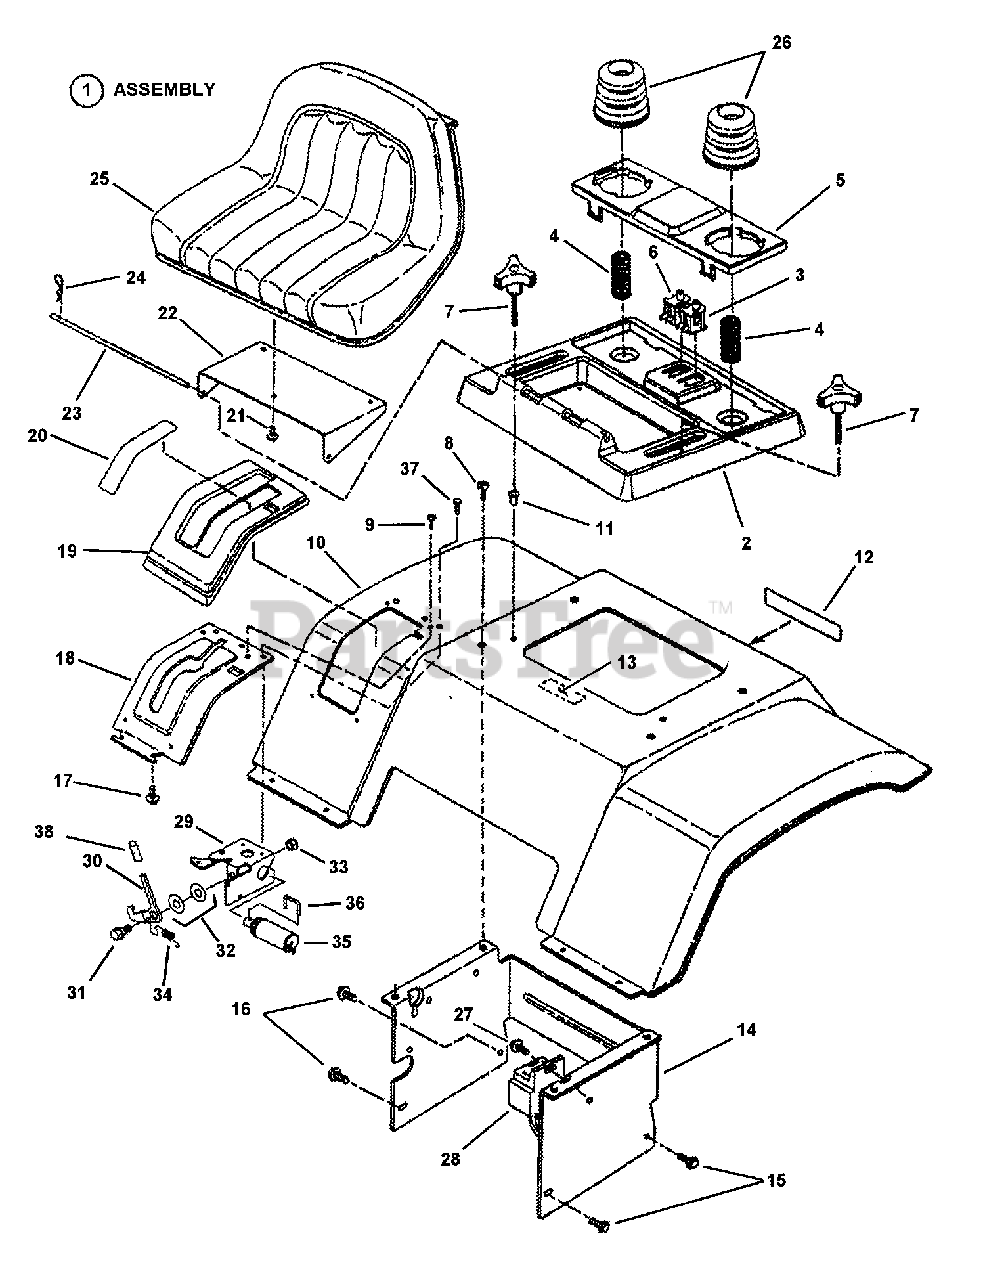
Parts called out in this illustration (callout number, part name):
1	ASSEMBLY, Seat Support-Electric PTO (Incl. items 2 thru 6)
2	SUPPORT, Seat- Electric Clutch
3	SWITCH, Seat, Gray (NC)
4	SPRING, Cushion Holder
5	HOLDER, Seat Cushion Electric Clutch
6	SWITCH, Seat
7	KNOB, 3 Prong 5/16-18 x 2" Stud
8	SCREW, 5/16-18 x 5/8" Truss Head (Torx)
9	SCREW, 1/4-20 x 5/8" Hex Washer Self-Tap
10	SEAT PAN, Tractor- "No Mow in Reverse" Fender
11	RIV-NUT, 5/16-18 Round
12	DECAL, Snapper- Hood- 3D, Silver Letters
13	DECAL, Caution-Battery Installation, Fender
14	SUPPORT, Fender, Electric Clutch-K 46
15	SCREW, 5/16-18 x 5/8" Hex Washer Head, Swage Form
16	SCREW, 5/16-18 x 1-1/4" Swage
17	SCREW, #10-16 x 1/2 HXWA
18	QUADRANT- Shift- No Mow in Reverse
19	COVER, Shift (Black)
20	DECAL, Shift Cover Hydro
21	BOLT, 5/16-18 x 1/2" Hex Flange Lock, GR5
22	SUPPORT, Seat, Upper
23	ROD, Seat Hinge
24	HAIR PIN, 3/32 x 1.5"
25	SEAT, Operator, V560 (shown)
26	SPRING COVER, Rubber
27	SCREW, #10-24 x 1/2" Hex Washer Self-Tap (Torx)
28	RECEPTACLE, Female Wire Harness Relay
29	ASSEMBLY, Stop Latch- Lock Out
30	LATCH, Overide-No Mow in Reverse
31	SHOULDER BOLT, 5/16-18
32	SHIM-WASHER
33	NUT, 5/16-18-3B Hex Nyloc
34	SPRING, Extension- Manual No Mow
35	SOLENOID, Electric
36	ROD, Connecting- No Mow in Reverse
37	SCREW, #10-24 x 1/2" Hex Washer Self-Tap (Torx)
38	CAP - Vinyl
